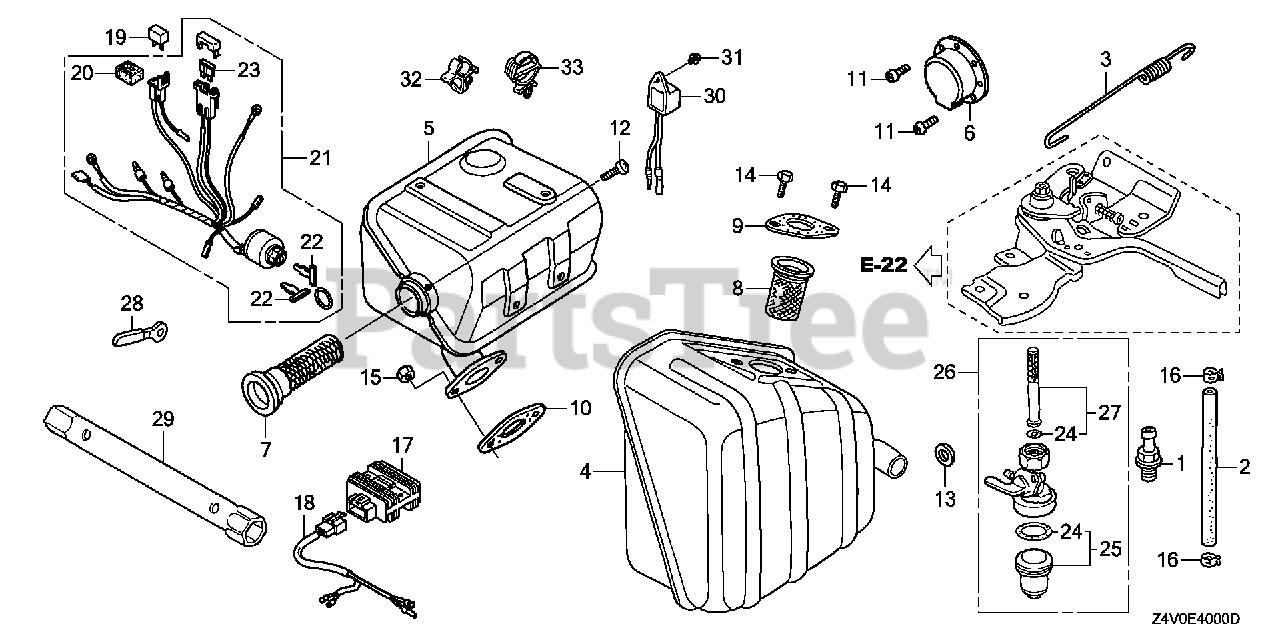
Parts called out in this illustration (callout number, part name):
9	GASKET, MUFFLER
15	NUT, HEX. (8MM)
19	RECTIFIER ASSY., SILICON (SHINDENGEN)
20	SUSPENSION, CONNECTOR
21	SWITCH ASSY., COMBINATION
22	KEY
23	FUSE, BLADE (5A)
